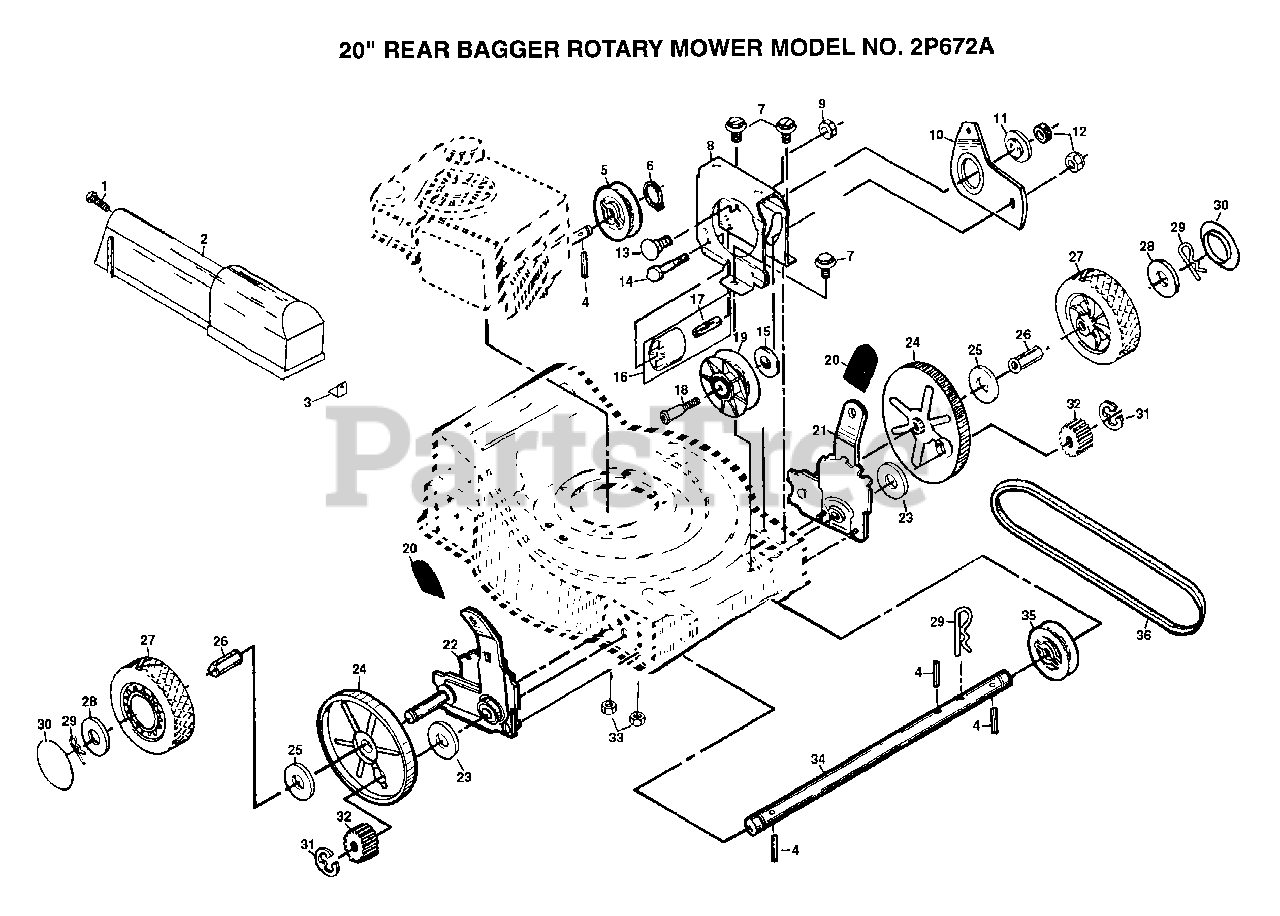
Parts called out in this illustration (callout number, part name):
1	SCREW HXHD 10-24
2	COVER.DRV.B&S.20
3	FASTNER PUSH DRCV
4	DRIVE PAWL
6	RETAINING RING ST
7	SCREW
8	"CLUTCH,FRAME"
9	LOCKNUT
11	SPACER PM
12	LOCKNUT
13	CARRIAGE BOLT
14	BOLT 1/4-20-1 1/2
15	SPACER PM
17	IDLER SPACER
18	SHOULDER BOLT
19	IDLER PULLEY
20	KNOB PM
23	WASHER PM
24	DUST SHROUD PM
25	WASHER FLUT
26	BUSHING.HEX
27	WHEEL.8X2.LP.PR
28	WASHER
29	RETAINER CLIP PM
30	HUB CAP
31	E-RING.7/16.RE.
32	PINION.GEAR
34	SHAFT.DRIVE.17.81
35	DRIVE PULLEY PM
